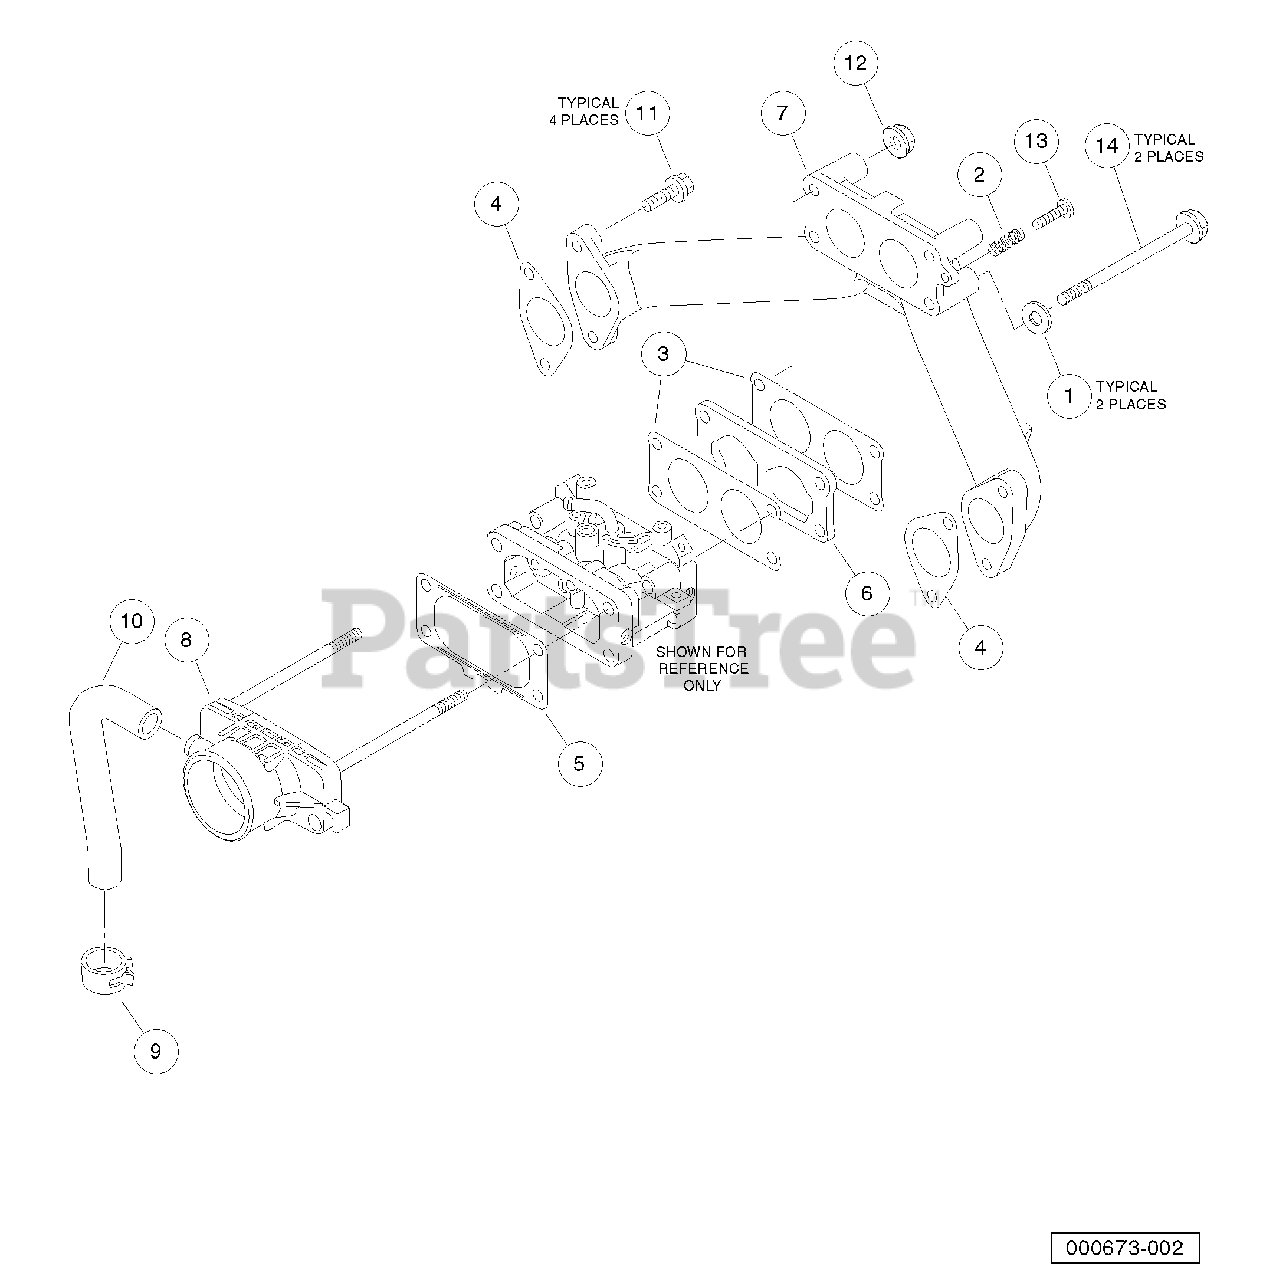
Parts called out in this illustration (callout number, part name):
1	Washer, M6 Flat
2	Spring, Fh
3	Gasket, Carburetor, Fh
4	Gasket, Manifold, Fh
5	Gasket, Air Filter, Fh
6	Insulator, Manifold, Fh
7	Manifold, Intake, Fh
8	Pipe, Intake Adapter, Fh
9	Clamp, Crankcase Vent, Fh
10	Tube, Crankcase Vent, Fh
11	Bolt, Flanged, M6 X 20, Kaw
12	Nut, Carburetor, M6
13	Screw, Carburetor, M4 X 20
14	Bolt, Flg, Carburetor, M6x105
